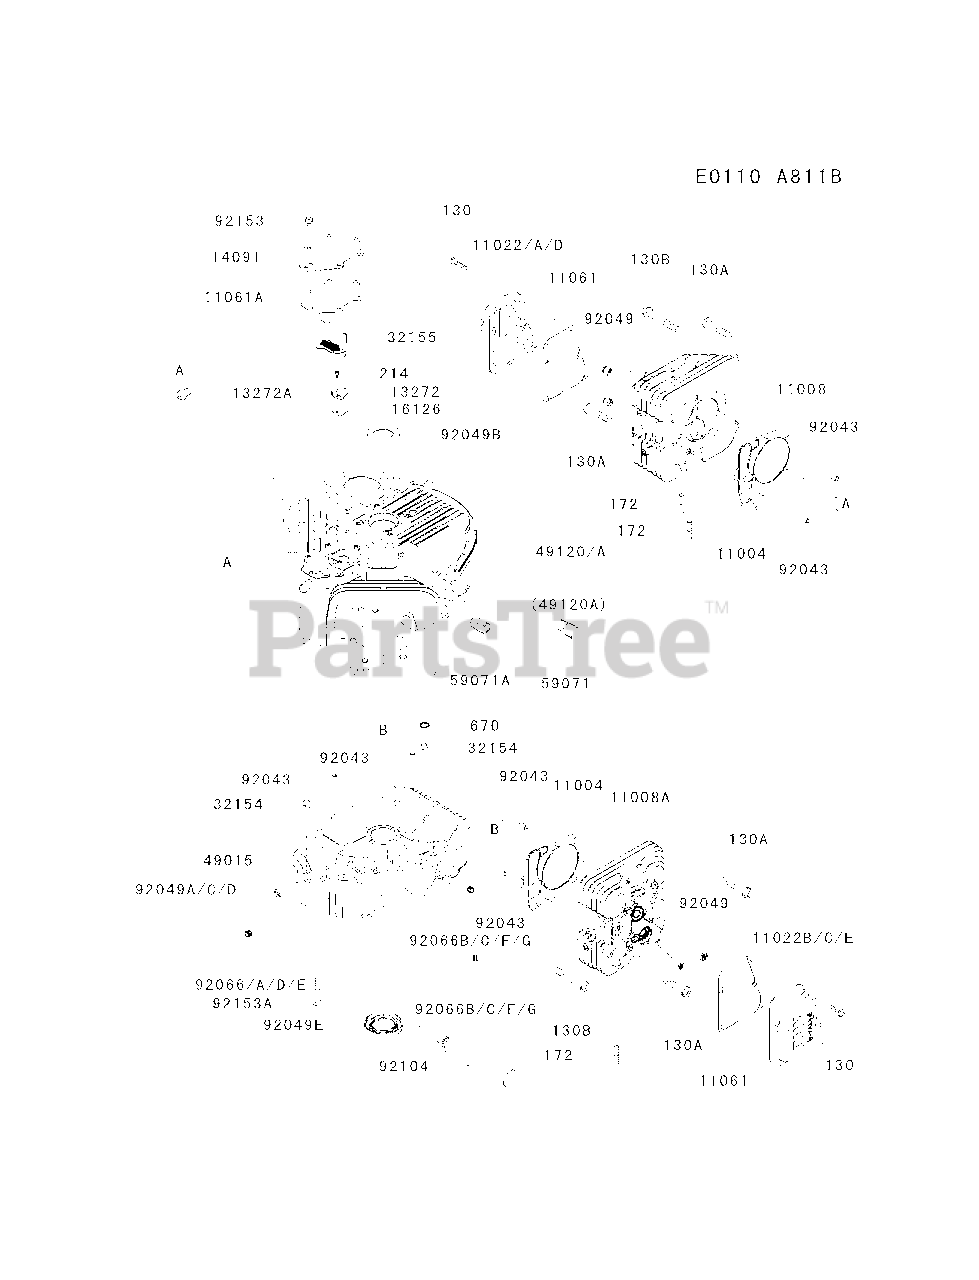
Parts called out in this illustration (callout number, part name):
130	BOLT-FLANGED,6X25
130A	BOLT-FLANGED,10X50
130B	BOLT-FLANGED,10X65
172	BOLT-STUD,8X18
214	SCREW-PAN+-,4X8
670	O RING,11MM
